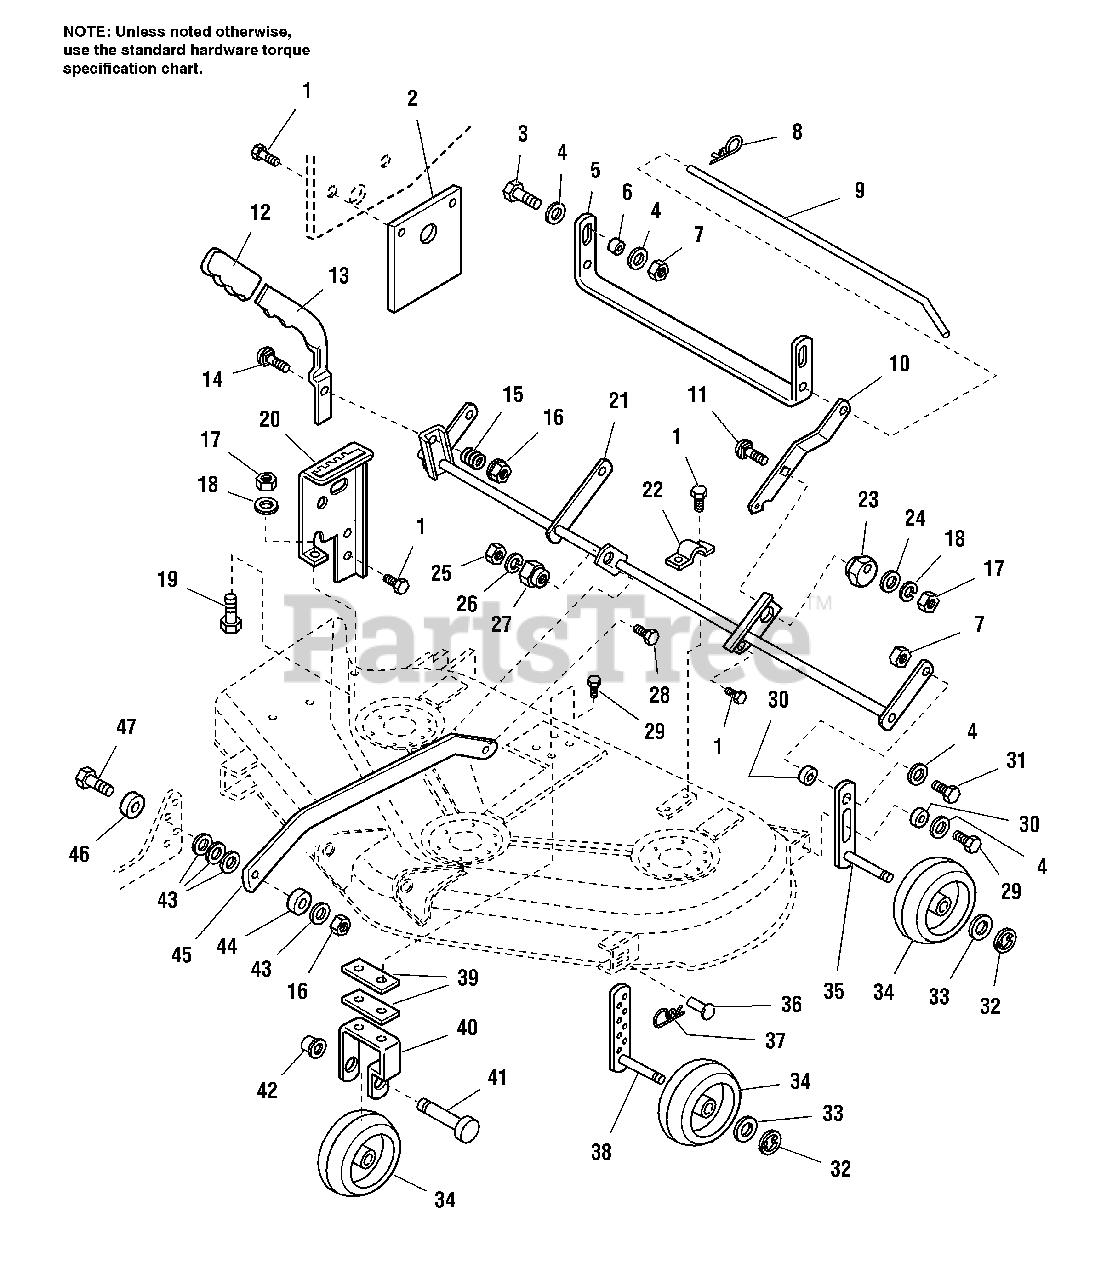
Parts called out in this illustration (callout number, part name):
1	CAPSCREW, Taptite Hex Washer Hd, 5/16-18 x 3/4
2	BRACKET, Upstop
3	CAPSCREW, Hex Hd, 5/16-18 x 1-1/4
4	WASHER, 5/16
5	BRACKET,"U"
7	NUT, Hex Lock, 5/16-18
8	CLIP, Spring
9	ROD, Transport
11	CARRIAGE BOLT, 5/16-18 x 1-1/4
13	ARM, Adjustment
14	CARRIAGE BOLT, 3/8-16 x 1-3/4
16	NUT, Hex Flange Whiz Lock, 3/8-16
17	NUT, Hex, Full, 5/16-18
18	LOCKWASHER, 5/16
19	CAPSCREW, Hex Hd, 5/16-18 x 3/4
21	ARM ASSEMBLY, Rocker
22	STRAP
24	WASHER, 5/16
25	NUT, Hex, 3/8
26	WASHER, Lock, 3/8
27	NUT, Hex Adjusting, .99 DIA .687
28	CARRIAGE BOLT, 3/8-16 x 1-1/2
29	CAPSCREW, Taptite Hex Washer Hd, 5/16-18 x 1
31	CAPSCREW, Hex Hd, 5/16-18 x 1
32	E-RING, 1/2
33	WASHER, 1/2
34	WHEEL, Gauge
35	ARM ASSEMBLY
37	CLIP, Hairpin
38	ARM ASSEMBLY, Adjustable
39	STRAP
40	BRACKET, Gauge Wheel
41	ROD, Mower Hitch
42	NUT, Push, 1/2
43	WASHER, 3/8
45	ARM, Pitch
47	CAPSCREW, Hex Hd., 3/8-16 x 2, Grade 5
